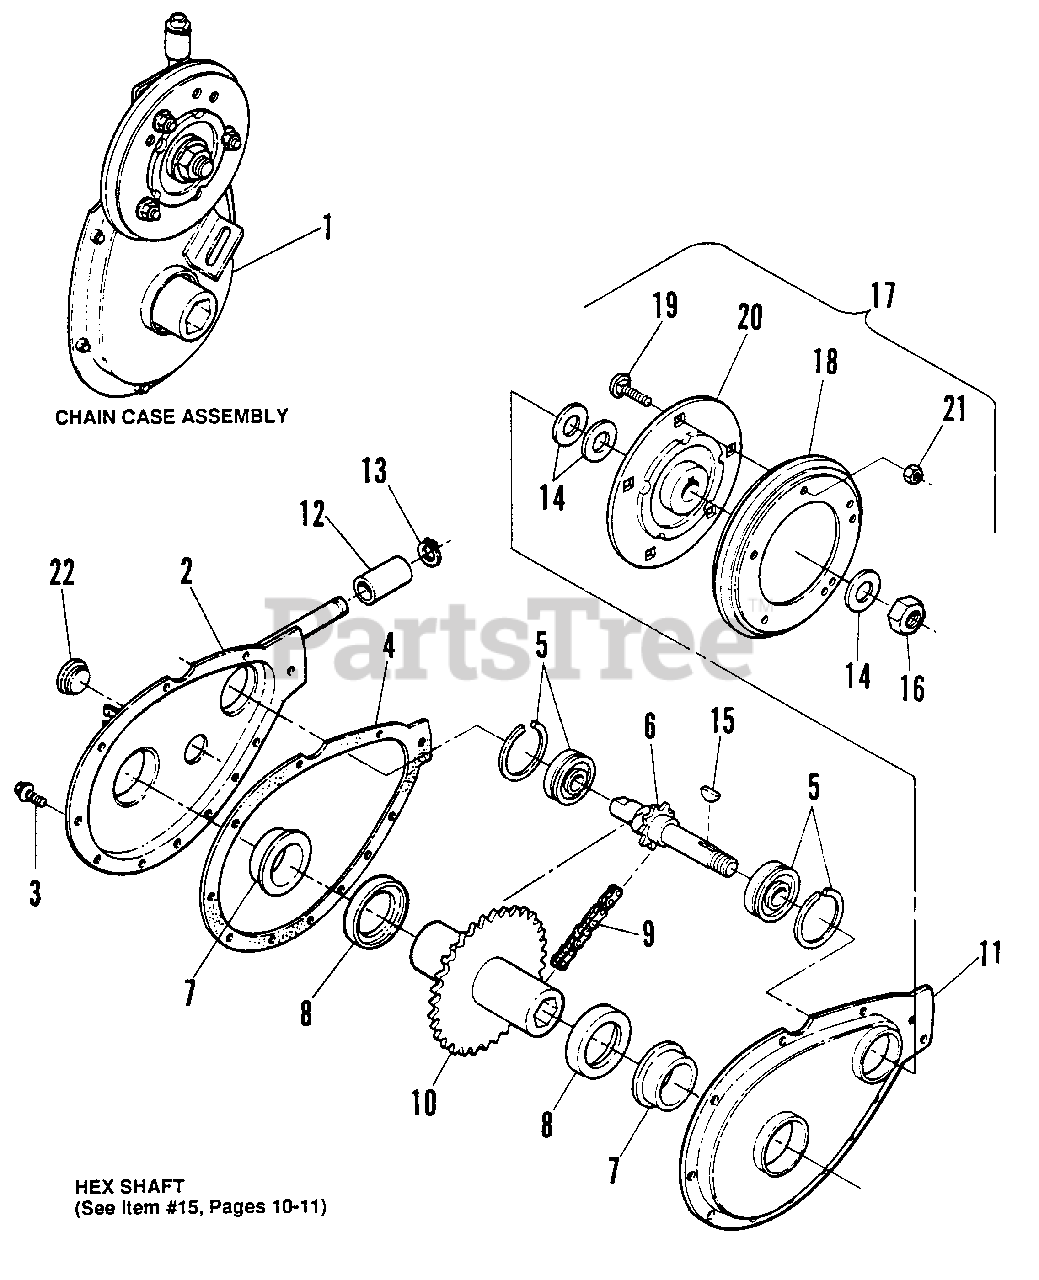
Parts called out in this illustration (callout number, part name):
1	ASSEMBLY, Chain Case
2	COVER, Sprocket
3	SCREW, #10-24 x 1/2" Hex Washer Self-Tap (Torx)
4	GASKET
5	BEARING, Ball
6	ASSEMBLY, Shaft & Sprocket
7	BUSHING
8	WASHER, Thrust
9	CHAIN
10	ASSEMBLY, Hub & Sprocket
11	CHASE, Sprocket
12	ROLLER
13	RING, Retaining
14	WASHER, Belleville
15	KEY, 1/8 x 5/8" Woodruff
16	NUT, 5/8-18 Hex Center Lock
17	ASSEMBLY, Drive Disc
18	DISC, Driven (R/B 7018782)
19	BOLT, 5/16-18 x 1/2" Short Neck Carriage
20	HUB
21	NUT, 5/16-18 Hex Flange Lock
22	PLUG
